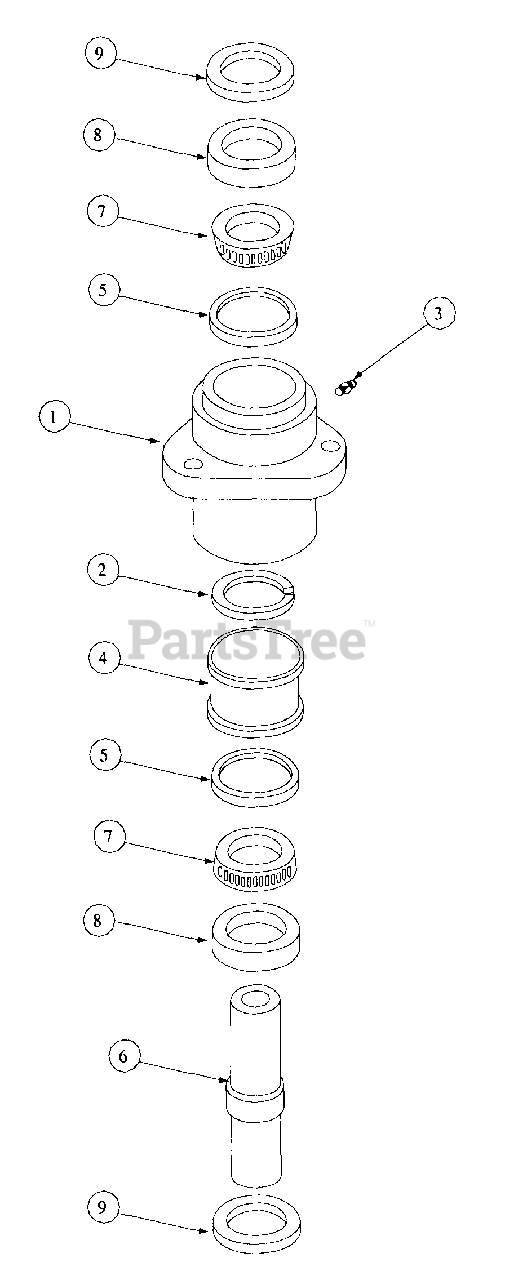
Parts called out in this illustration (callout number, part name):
1	Spindle Housing
2	Spacer Bearing
3	Grease Fitting
5	Cup Bearing
6	Shaft Blade Spindle
7	Cone Bearing
8	Ring Seal
9	Oil Seal
